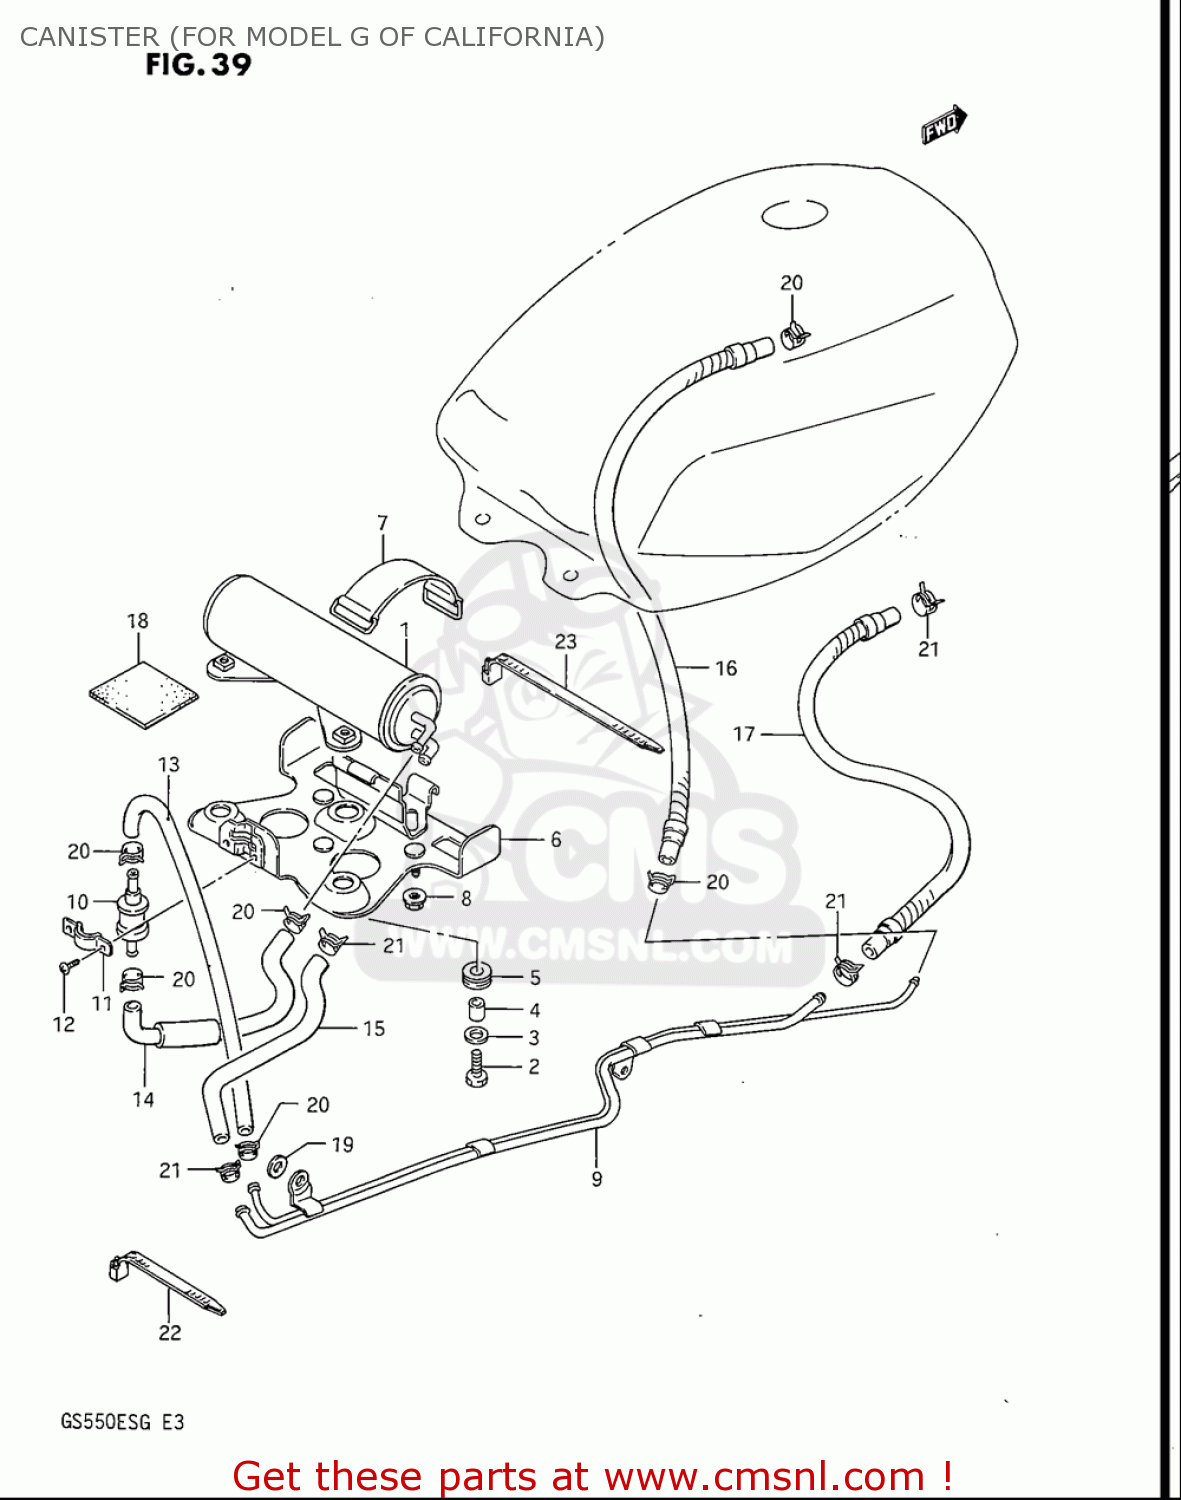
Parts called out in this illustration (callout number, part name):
2	BOLT
3	WASHER(6.5X18X1.6)
4	SPACER(6.1X9X7.5)
5	CUSHION
7	BAND
8	NUT
10	VALVE,FUEL TANK BREATHER
11	PLATE,FUEL TANK BREATHER NO.2
12	SCREW
19	WASHER (8.5X16X2.6)
20	CLIP
21	CLIP
22	CLAMP(L:95)
23	CLAMP(L:165)
